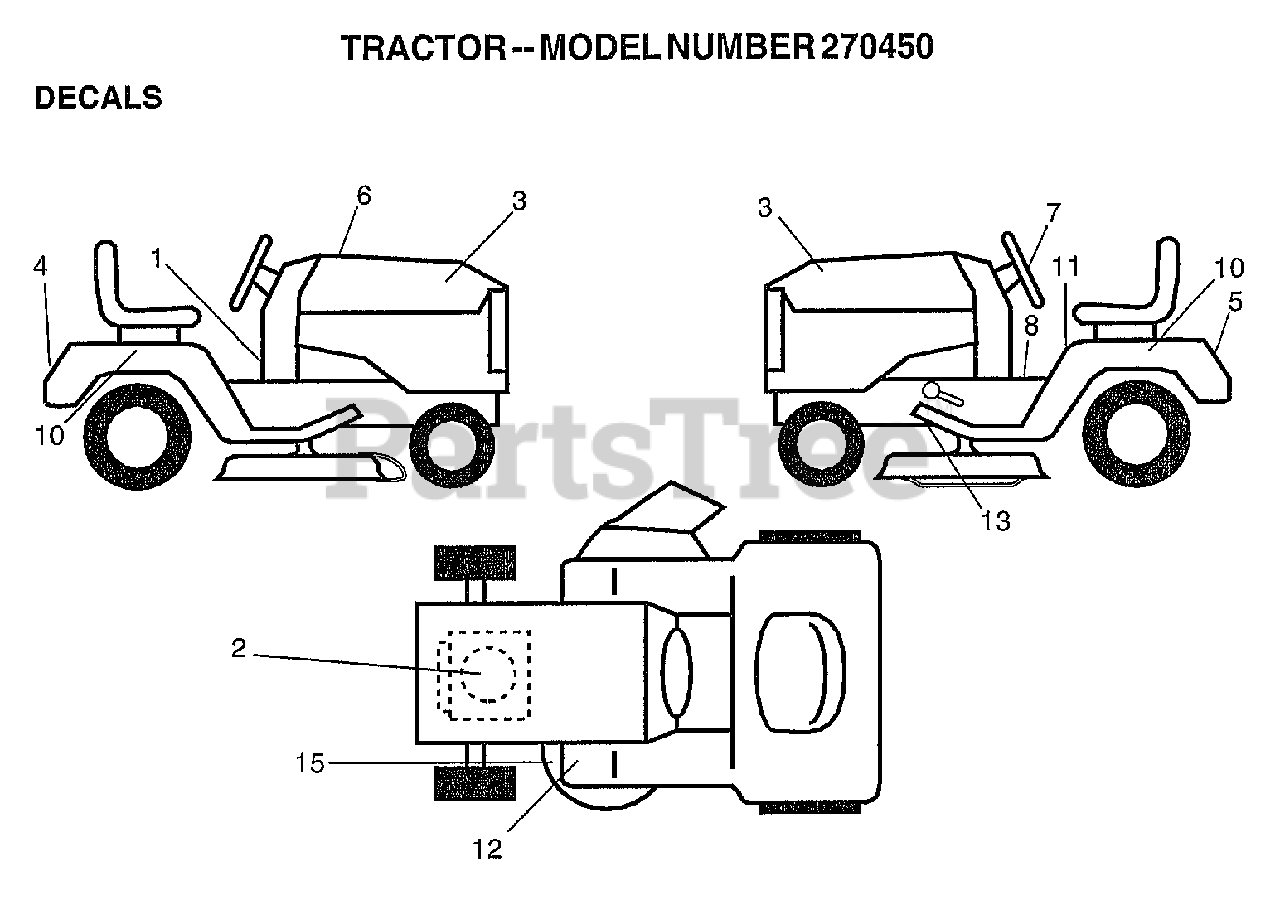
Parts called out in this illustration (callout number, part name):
1	DECAL,DASHL
2	DECAL, ENGINE
3	DECAL, HOOD
4	DECAL, FENDER
5	DECAL.BATRY.3-3908
6	DECAL, REPLACEMENT PARTS
7	DECAL, STEERING
8	"DECAL DASH,OPER."
10	DECAL, FENDER
11	"DECAL-FENDER,DANG"
13	DECAL.BELT-V.SCHM
15	DECAL
